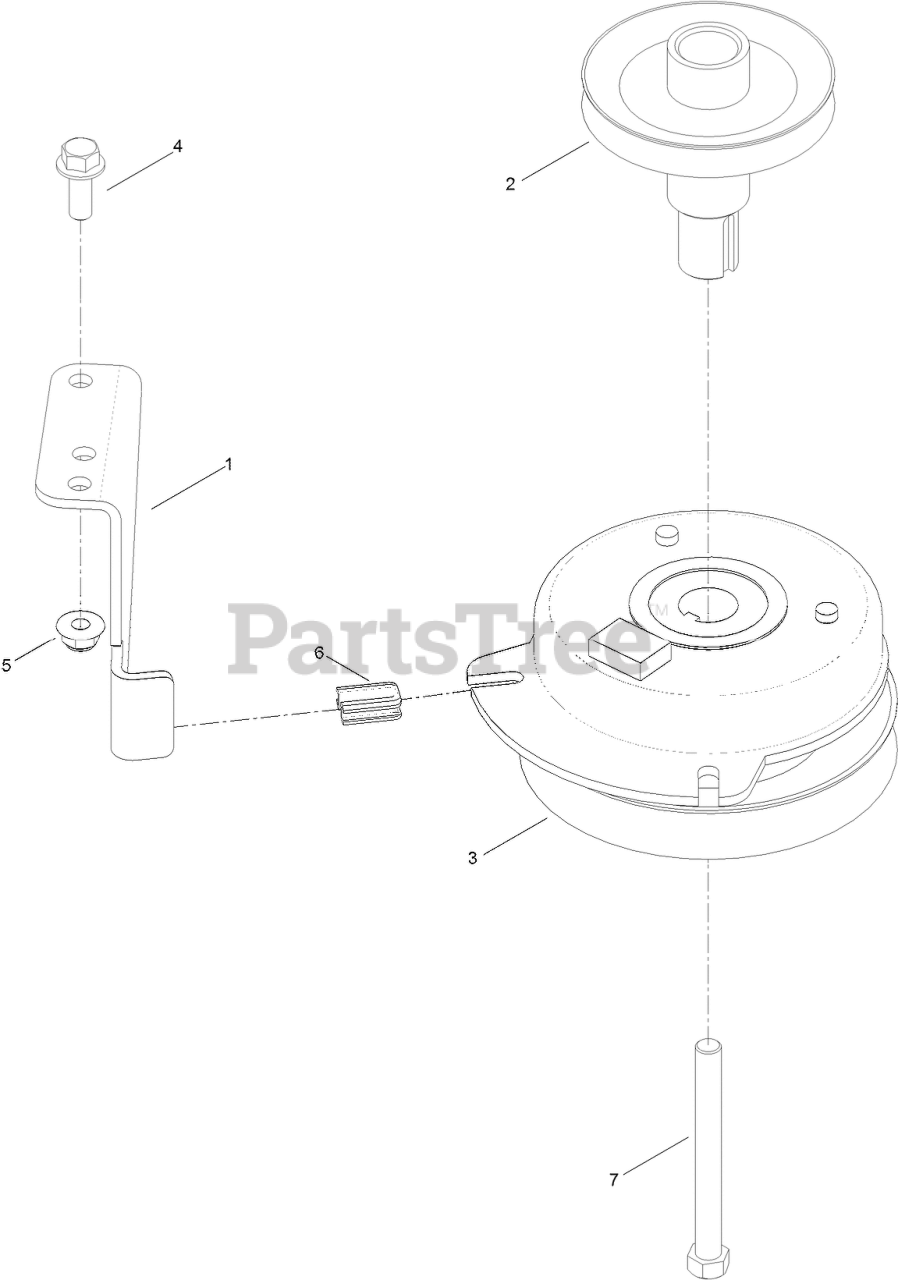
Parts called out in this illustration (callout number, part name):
1	STOP-CLUTCH (WIDE)
2	PULLEY-ENGINE
3	CLUTCH-PTO
4	SCREW-HHF
5	NUT-HF, NI
6	ISOLATOR-CLUTCH
7	SCREW-HH
